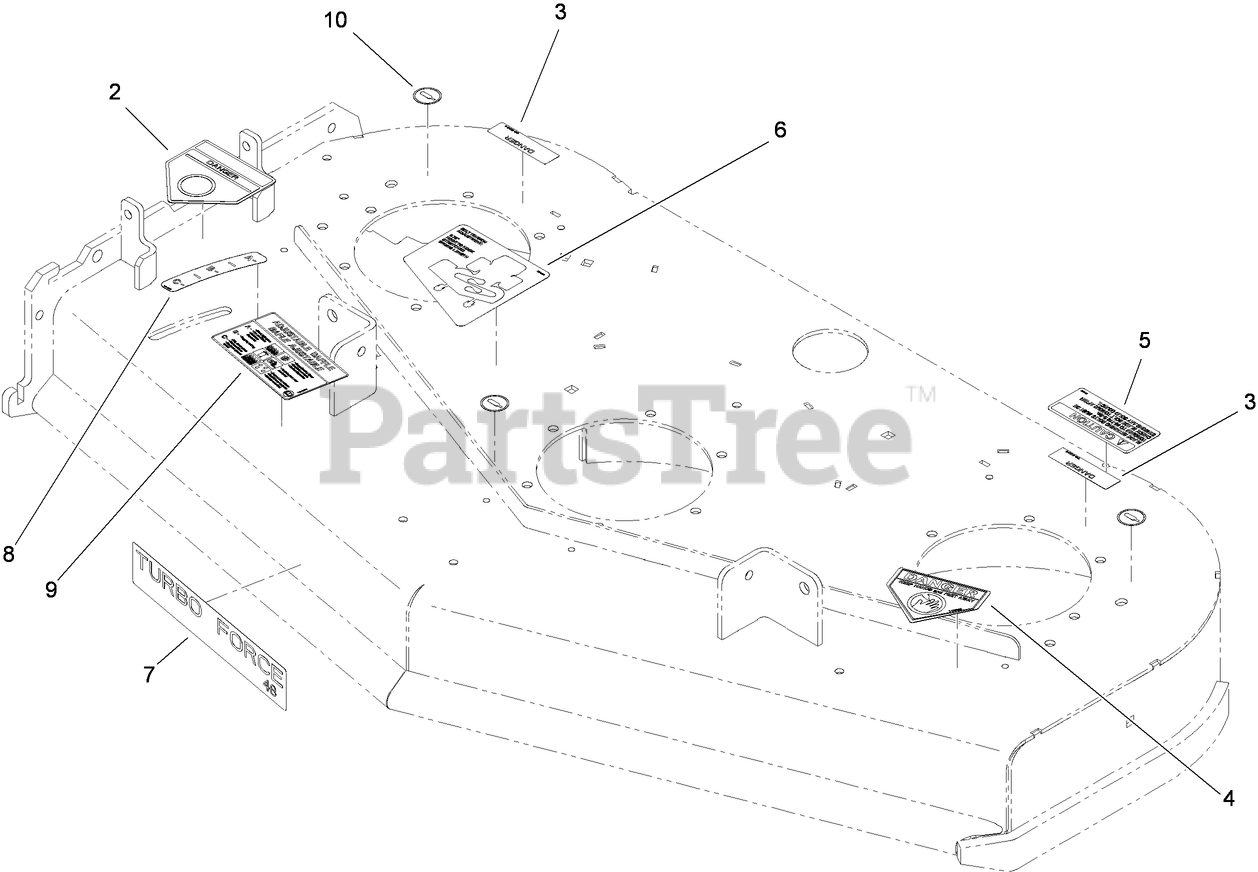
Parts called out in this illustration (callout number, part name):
2	DECAL-DANGER
3	DECAL-COVER, MISSING
4	DECAL-DANGER
5	DECAL-TORQUE
6	DECAL-TENSION, BELT
8	DECAL-SETTING, BAFFLE
9	DECAL-ADJUSTMENT, BAFFLE
10	DECAL-GREASE
